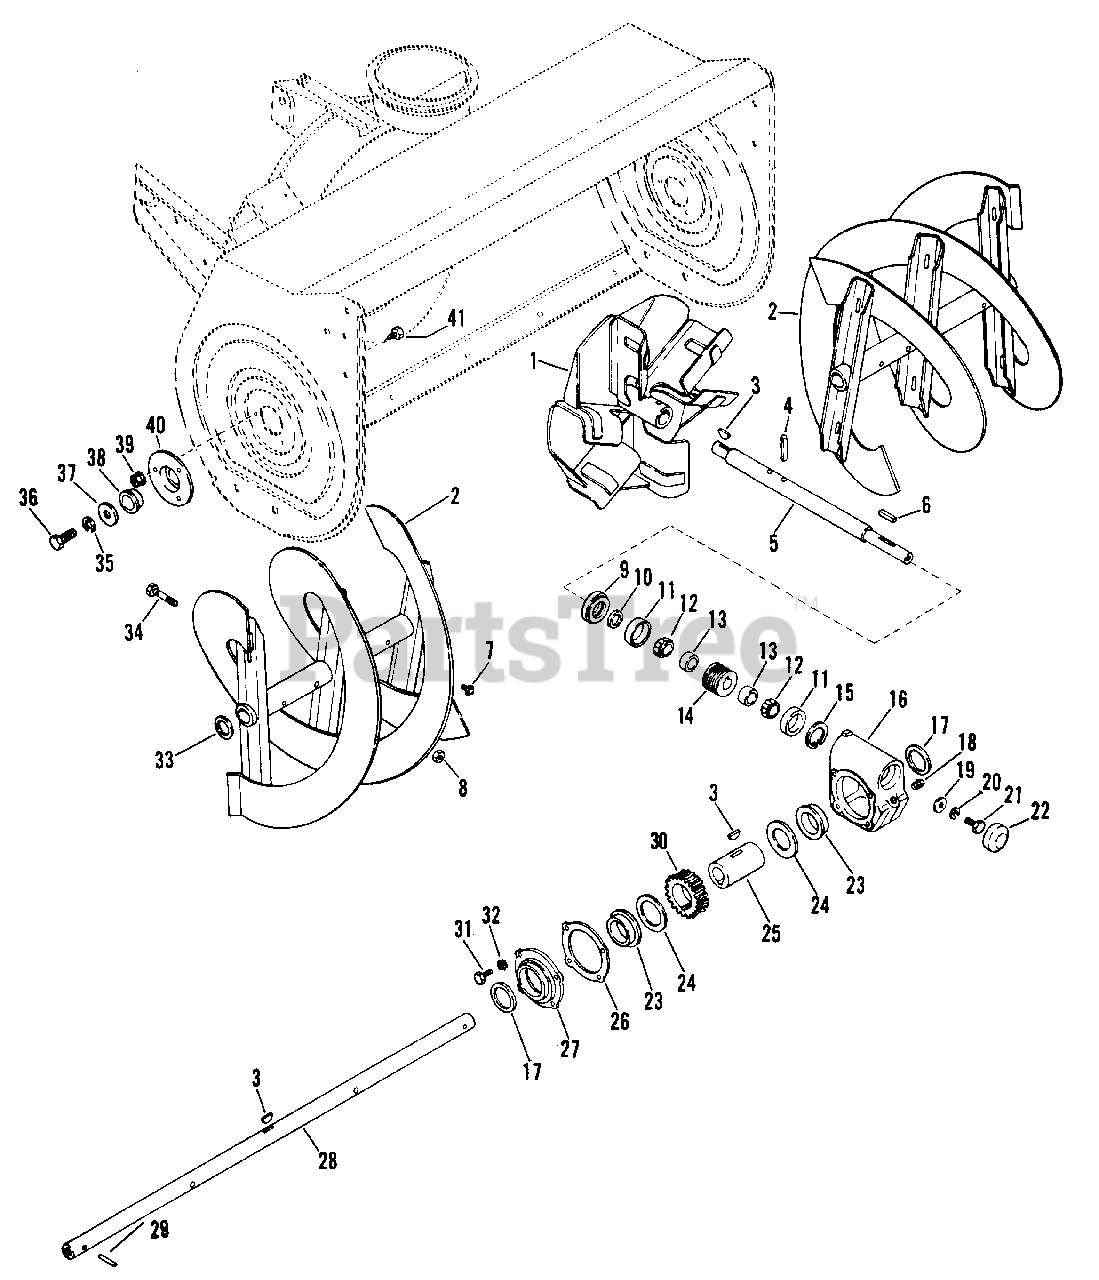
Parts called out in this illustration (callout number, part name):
1	Fan
2	Rake, Right
2	Rake, Left
3	Key, Woodruff .250x.875 HRD #A
4	Pin, Roll .312x1.75
5	Shaft, Worm
6	Key, Straight SAE 1035
7	Fitting, Lube 1/4-28
8	Nut, Lock 5/16-18
9	Plug, Adjustment
10	Seal
11	Cup, Bearing
12	Cone, Bearing
13	Spacer, Bearing
14	Worm
15	Snap Ring, Internal
16	Gear Case
17	Seal, 1-5/8 Nom.
18	Plug, Pipe
19	Washer, Flat .344x.688x.065
20	Washer, Lock 5/16 SP
21	Bolt, Hex 5/16-18x.75
22	Cap, Dust
23	Bushing, Flange 1.62 x1.87x11
24	Washer, 1.625x2.500x.012
25	Shaft, Gear Case
26	Gasket
27	Cover, Gear Case
28	Shaft, Rake
29	Pin, Spring .187x.500
30	Gear, Worm
31	Bolt, Hex 1/4-20x.875
32	Washer, Lock 1/4
33	Washer, 1.00x1.50x.06
34	Bolt, Shear
35	Washer, Lock 1/2
36	Bolt, Hex 1/2-13x1.00
37	Washer, Flat .515x1.441x.1
38	Bushing, Flange 1.00x1.125x.625
39	Nut, Lock 1/4-20
40	Support, Bearing
41	Bolt, Rib Neck 1/4-20x.50
